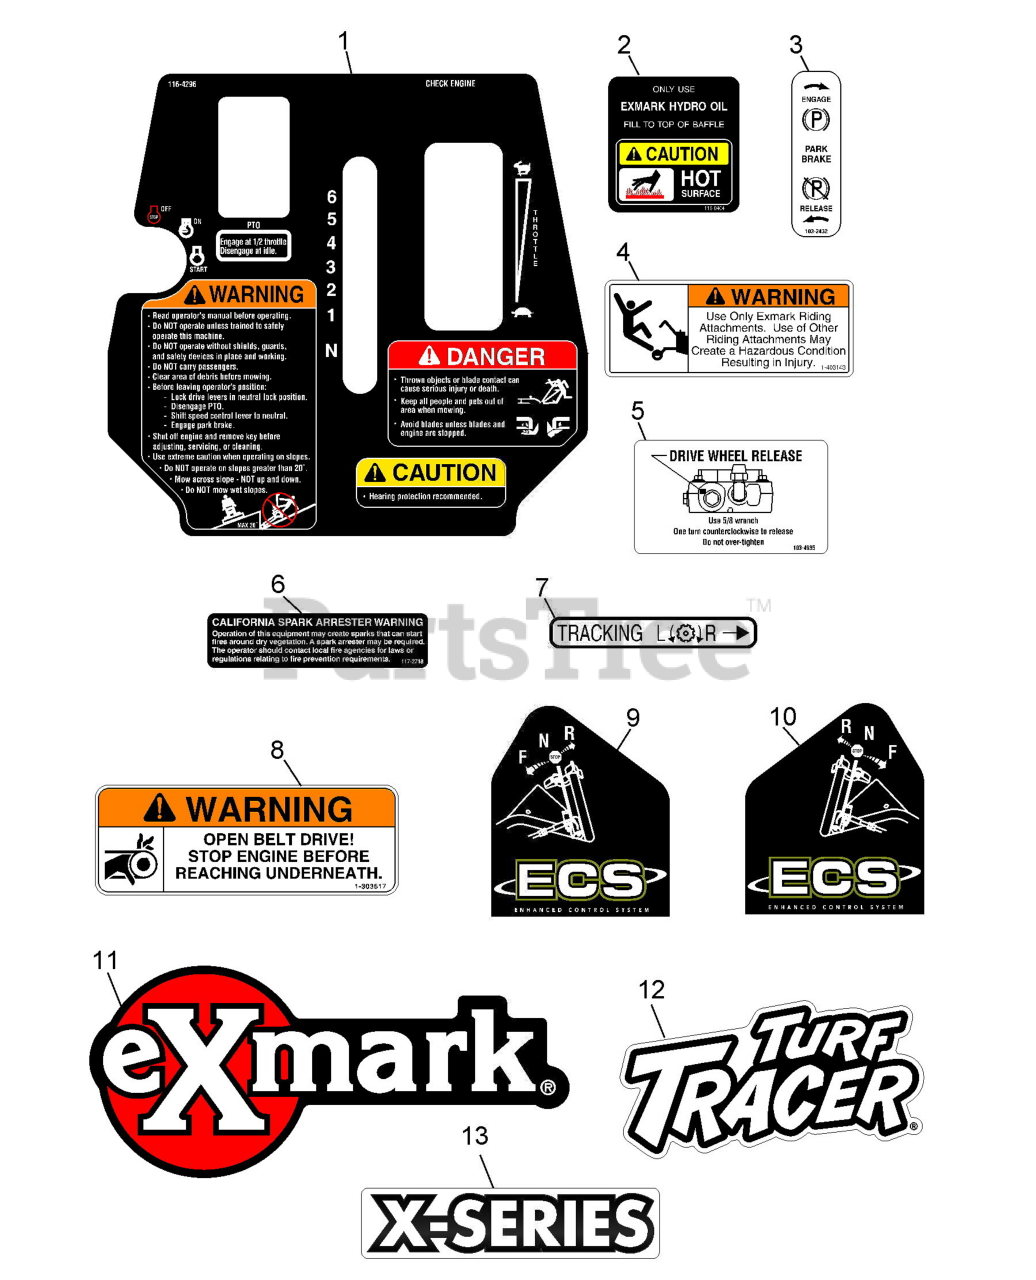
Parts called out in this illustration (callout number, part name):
1	DECAL,CONSOLE TTX
2	DECAL-HYDRAULIC TANK
3	DECAL,SULKY WARNING
4	DECAL,PARKING BRAKE
5	DECAL,DRIVE RELEASE
6	DECAL-ARRESTER, SPARK
7	DECAL,TRACKING ADJUST
8	DECAL,BELT DRIVE
9	DECAL,LH ECS INSTRUCTION
10	DECAL,RH ECS INSTRUCTION
11	DECAL,EXMARK LOGO
12	DECAL,TTH MODEL
13	DECAL-X-SERIES
